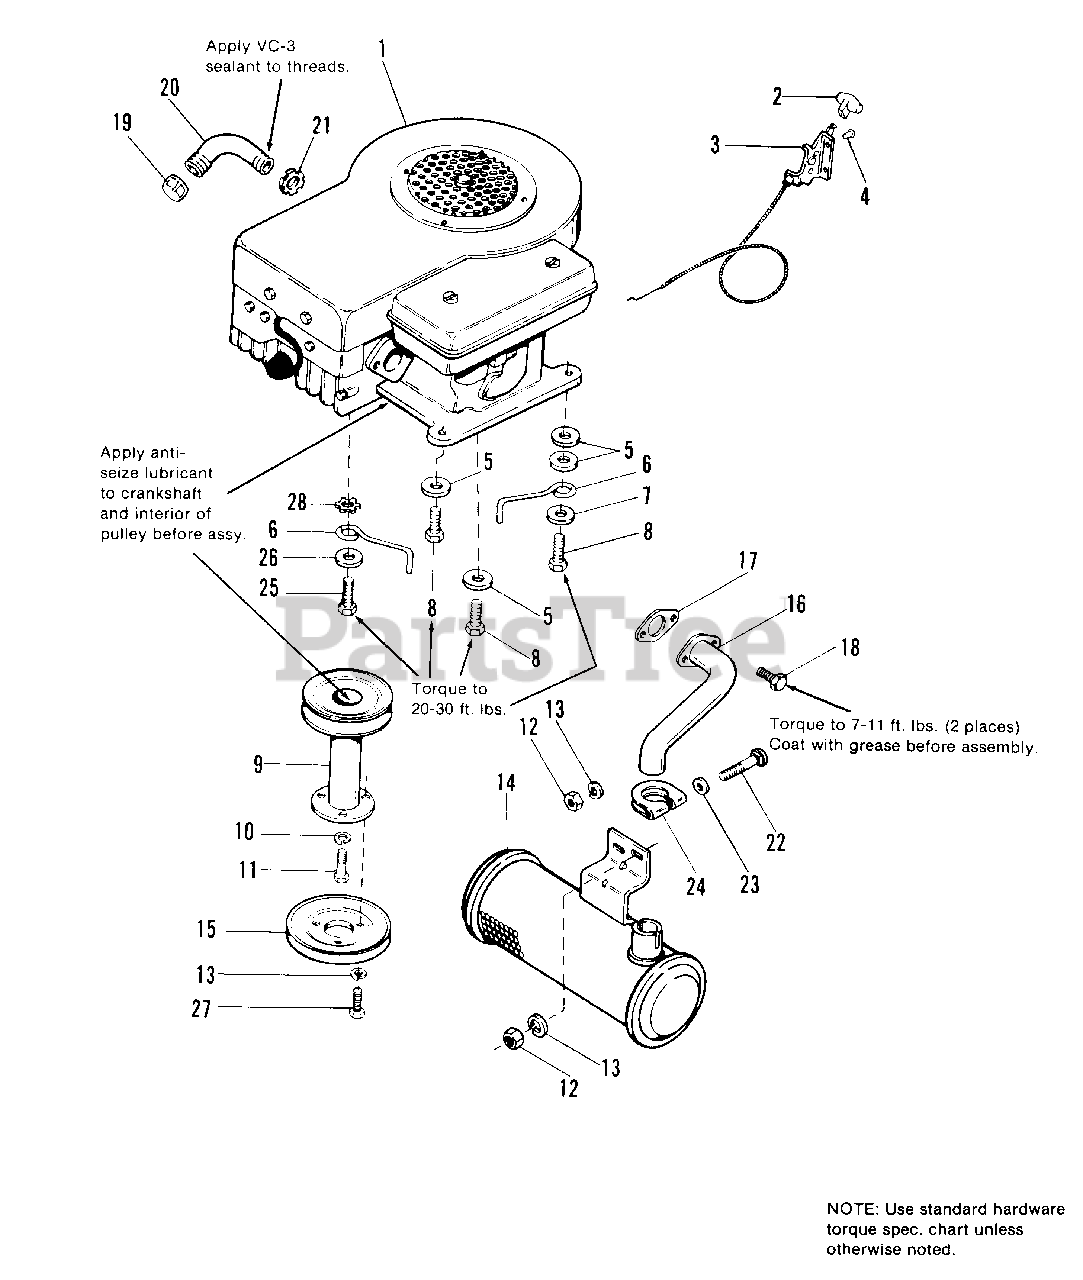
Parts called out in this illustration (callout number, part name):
1	ENGINE, 12 HP Briggs & Stratton
2	KNOB, Throttle
3	CONTROL ASSY., Throttle
4	RIVET, Pop, 1/4
5	WASHER, Plain, 3/8
7	WASHER, 3/8
8	SCREW, Taptite, 3/8-16 x 1-1/2
9	PULLEY ASSY., Engine
10	LOCKWASHER, 7/16
11	CAPSCREW, Hex, 7/16-20 x 1-1/4
12	NUT, Hex, 5/16-18
13	LOCKWASHER, 5/16
16	PIPE, Exhaust
17	GASKET, Muffler
18	SCREW, Whizlock, 5/16-18 x 3/4
20	PIPE, Oil Drain (Incl. Ref. Nos. 19, 20 & 21)
21	LOCKNUT, Conduit
22	BOLT, Carriage 5/16-18 x 3-2//4
23	WASHER, 5/16
25	SCREW, Taptite, 3/8-16 x 1-1/2 Zinc Pltd.
26	WASHER, 3/8, Zinc Pltd.
27	CAPSCREW, Hex Hd., 5/16-18 x 1-1/2 Full Thrd.
28	LOCKWASHER, Ext. Tooth, 3/8, Zinc Pltd.
